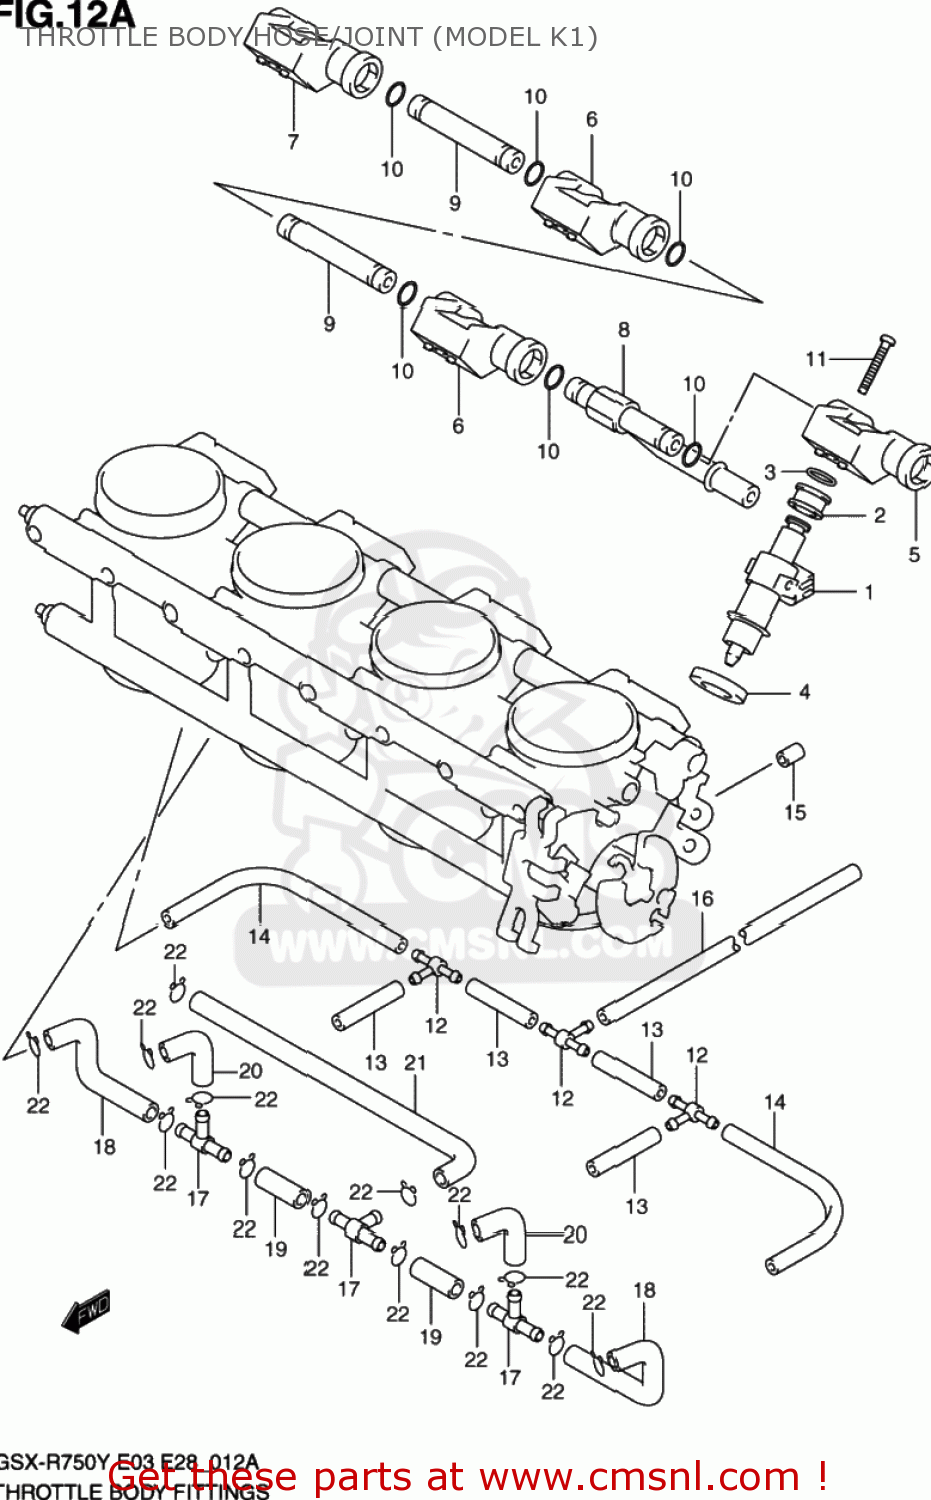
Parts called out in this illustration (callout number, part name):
1	INJECTOR ASSY
2	RING,CUSHION
3	O RING
4	RING,SEAL
5	JOINT,NO.1
6	JOINT,NO.2,3
7	JOINT,NO.4
8	JOINT
9	JOINT
10	O RING
11	SCREW
12	JOINT
13	HOSE,RUBBER(L:35)
14	HOSE,RUBBER(L:100)
15	CAP,RUBBER
16	HOSE,RUBBER(3X7X170)
17	JOINT
18	HOSE,RUBBER(L:80+25)
19	HOSE,RUBBER(L:35)
20	HOSE,RUBBER(L:30+30)
21	HOSE,RUBBER(L:200+30)
22	CLIP
